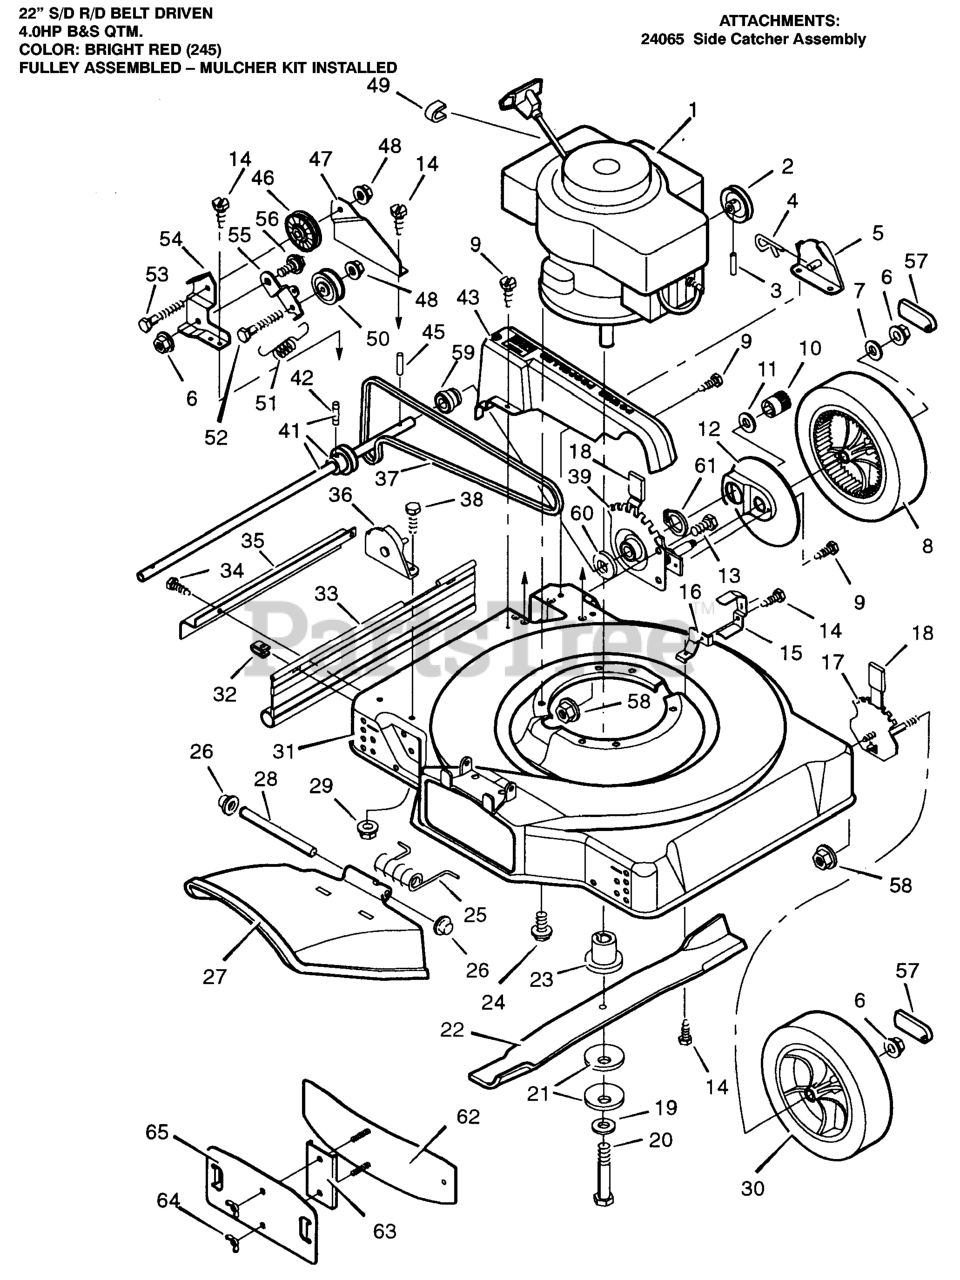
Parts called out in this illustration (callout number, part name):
2	Pulley
3	Pin, Spring
4	Pin, Hair
5	Bracket, Left Handle
6	Nut
7	Washer
8	Wheel, Drive
10	Gear, Right Pinion
12	Cover, Dust
13	Bolt, Hex
15	Guide, Belt
16	Belt Guide, Briggs
17	Height Adjuster, Front
21	Washer, Belleville
23	Adapter, Blade
24	Bolt, Engine
25	Spring, Torsion
26	Push On Cap
27	Deflector, Chute
29	Nut
30	Wheel and Tire, Front
31	Housing
32	Retainer
33	Deflector, Rear
35	Guard, Axle
36	Bracket, Right Handle
37	Belt, Briggs & Stratton
39	Height Adjuster, Left
41	Axle, Pulley & Setscrew
42	Setscrew
43	Belt Guard, Briggs
45	Pin, Drive
46	Pulley, Idler
47	Support, Idler
48	Nut
49	Stop, Rope
50	Pulley, Idler
51	Spring, Extension
52	Bolt, Hex
53	Bolt, Hex
54	Bracket, Idler
55	Arm, Idler
56	Bolt, Shoulder
57	Cap, Hub
58	Nut, Flange
59	Bearing and Retainer
60	Washer, Belleville
61	Retainer Ring
62	Baffle
63	Spacer
64	Wingnut
